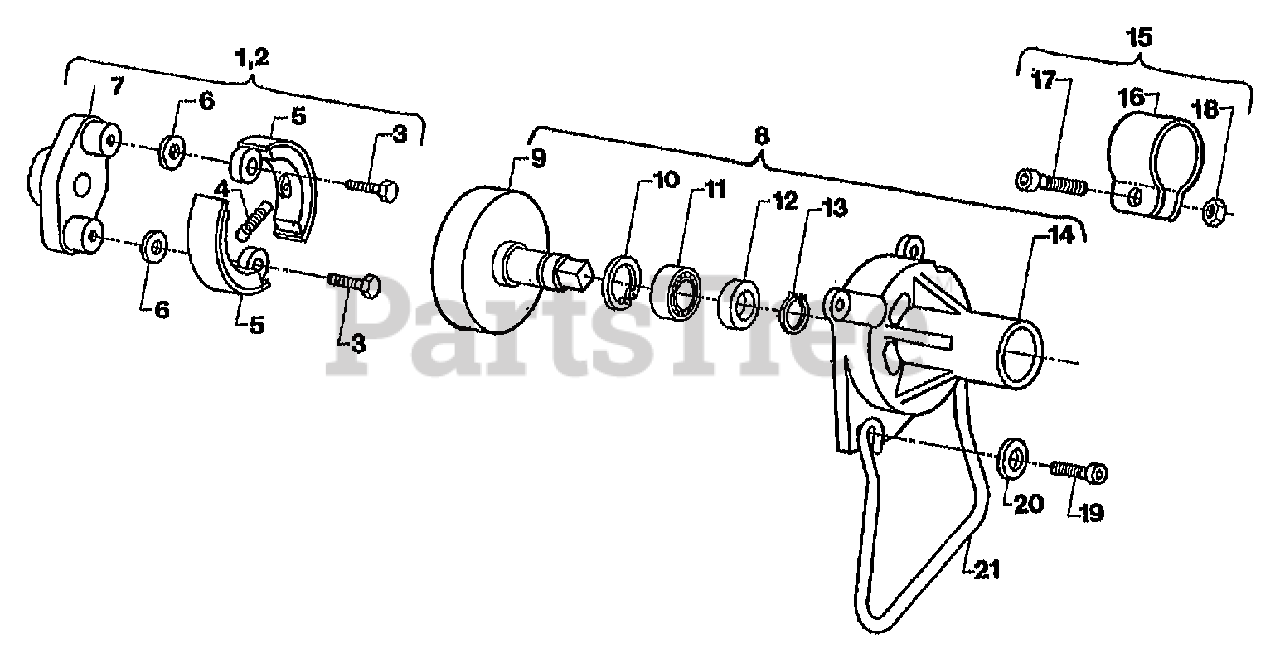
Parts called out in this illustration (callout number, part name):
1	ASSM-CLUTCH (COMPLETE) (INCL. 3-7)
2	ASSM-CLUTCH (COMPLETE) (INCL. 3-6)
3	SCREW, HEX, HD., CLUTCH
4	SPRING (GREEN)-CLUTCH
5	SHOE CLUTCH
6	WASHER, FLAT, 1/4" I.D. CLUTCH
7	ROTOR THREADED-CLUTCH
8	ASSM-CLUTCH HOUSING (INCL. 9-14)
9	ASSM-DRUM & ARBOR
10	RING-RETAINING
13	RING-RETAINING
14	HSG-CLUTCH W/BRG (INCL. 11-13)
15	KIT, CLAMP ASSEMBLY, (INCL. 16-18)
16	CLAMP
17	SCREW, 1/4"-20x3/4", SOCKET HD. CAP
18	NUT, 1/4"-20, CLAMP
19	SCR-HXSKT 1/4-20X.75
20	WASHER-MOTOR LEG
21	LEG-MOTOR
